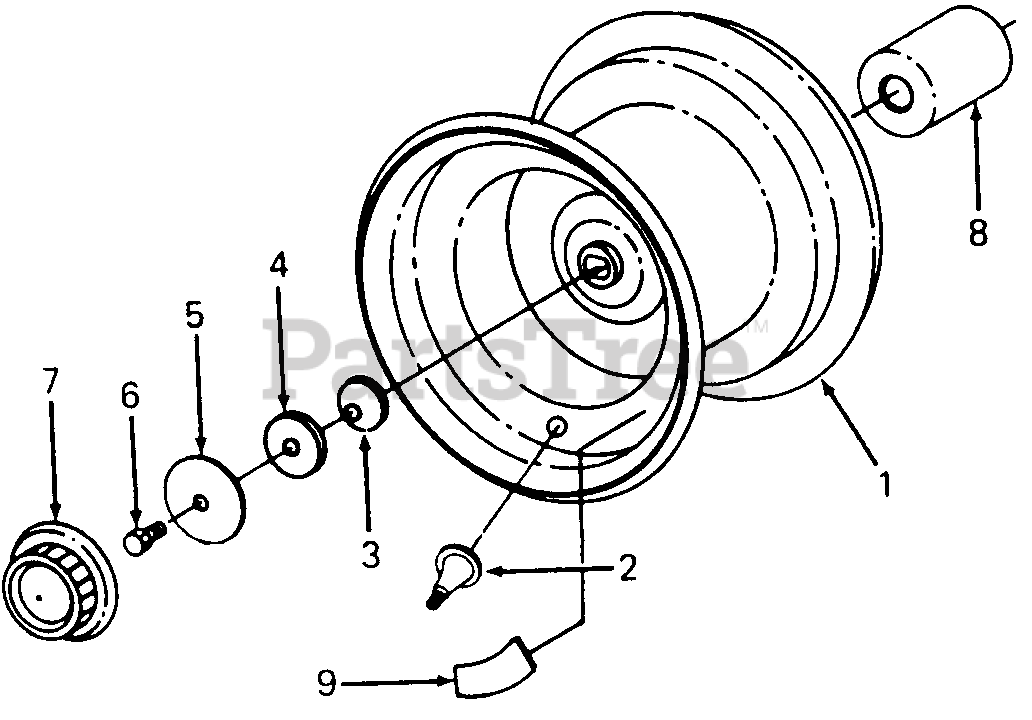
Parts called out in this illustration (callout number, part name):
1	Wheel Assy, Rear
2	Valve, Tubeless Type
3	Washer, .345 X .88 Belleville
4	Washer, .344 X 1.125 X .125
5	Washer, .406 X 1.92 X .06
6	Bolt, 5/16 X 1 GR5
7	Cap, Hub
8	Spacer, Transmission
9	Label, Inflation
